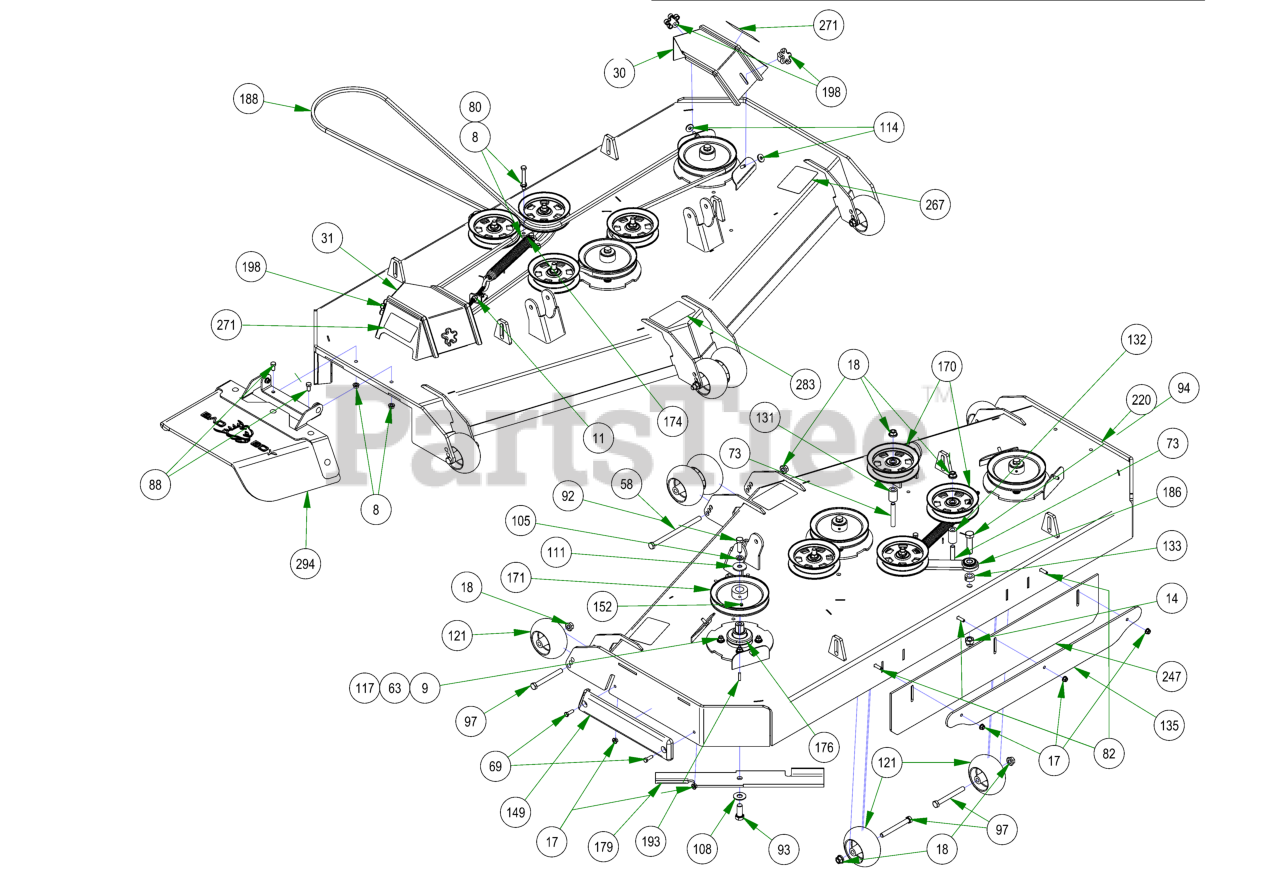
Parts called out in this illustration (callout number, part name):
8	3/8-16 HEX SERRATED FLANGE NUT HARD/ZINC
9	3/8-16 NYLON INSERT FLANGE LOCKNUT (GR.F) ZINC
11	3/8-16 HEX NUT ZINC
14	5/8-11 NYLON INSERT LOCKNUT ZINC
17	5/16-18 NYLON INSERT FLANGE LOCKNUT ZINC
18	1/2-13 NYLON INSERT FLANGE LOCKNUT ZINC
30	2019 72" Left Outlaw Gen2 Pulley Cover
31	2019 72" Right Outlaw Gen2 Pulley Cover
58	1/2-13 X 8 HEX CAP SCREW GR 5 ZINC
63	3/8-16 X 1-3/4 HEX C/S (GR.5) ZC
69	5/16-18 X 1 HEX CAP SCREW (GR.5) ZINC
73	1/2-13 X 3-1/2 HEX FLANGE BOLT (GR.8) ZINC
80	3/8-16 X 3 HEX CAP SCREW (GR.5) ZINC
82	5/16-18 X 1-1/4 CARRIAGE BOLT ZINC
83	4" 3/8-16 Eye Bolt
88	3/8-16 X 3/4 HEX CAP SCREW (GR.5) ZINC
92	1/2-20 X 1-1/2 HEX CAP SCREW (GR.5) ZINC
93	5/8-18 X 1-1/2 HEX CAP SCREW (GR.8) ZINC YELLOW
94	5/8-11 X 2-1/2 HEX CAP SCREW (GR.5) ZINC
97	1/2-13 X 4-1/2 HEX CAP SCREW (GR.5) ZINC
101	5/16-18 X 7/8 CARRIAGE BOLT ZINC
105	1/2 SPLIT LOCKWASHER (GR.8) ZINC/YELLOW
108	5/8 USS FLAT WASHER (1-3/4" OD) GR.8 ZINC YELLOW
111	1/2 BELLEVILLE WASHER (1-5/8 OD X .140 THK) ZINC
114	.360 ID X .983 OD X .120 THICK FLAT WASHER NYLON BLACK
117	5/16 USS FLAT WASHER (7/8 OD) ZINC
121	2019 Deck Wheel
131	.502 ID X .750 OD X 1.500 Long Spacer
132	1 3/4" Pulley Spacer
133	5/8 SOLID SHAFT COLLAR (W/1 SET SCREW) ZINC
135	61 Bolt in Baffle Deck v2 Stripping Plate
149	REVISED TRIM BUMPER_20180226
152	5/16-24 X 1/4 SOCKET SET SCREW (CUP PT) PLAIN
170	5-3/4 Idler Pulley
171	7" Deck Pulley
174	2019 Outlaw Gen2 Deck Spring
176	OUTLAW SPINDLE ASSEMBLY
179	72" High Lift Fusion Blade
181	2019 Deck Eye Bolt Tab
186	2019 Rebel Rogue Deck Idler
188	B202 Belt for 72" Outlaw
193	1/4 X 1 SQ MACHINERY KEY 1018 STL PLN
198	5/16" Knob
220	2019 Sloped 72" Deck
247	R Series Rubber For Deck
267	2018 72" Deck Decal
271	Danger Decal-Spindle/Discharge
283	2019 Rebel & Rogue Deck Belt Route Decal
294	2019 Outlaw Gen2 Chute Assembly
